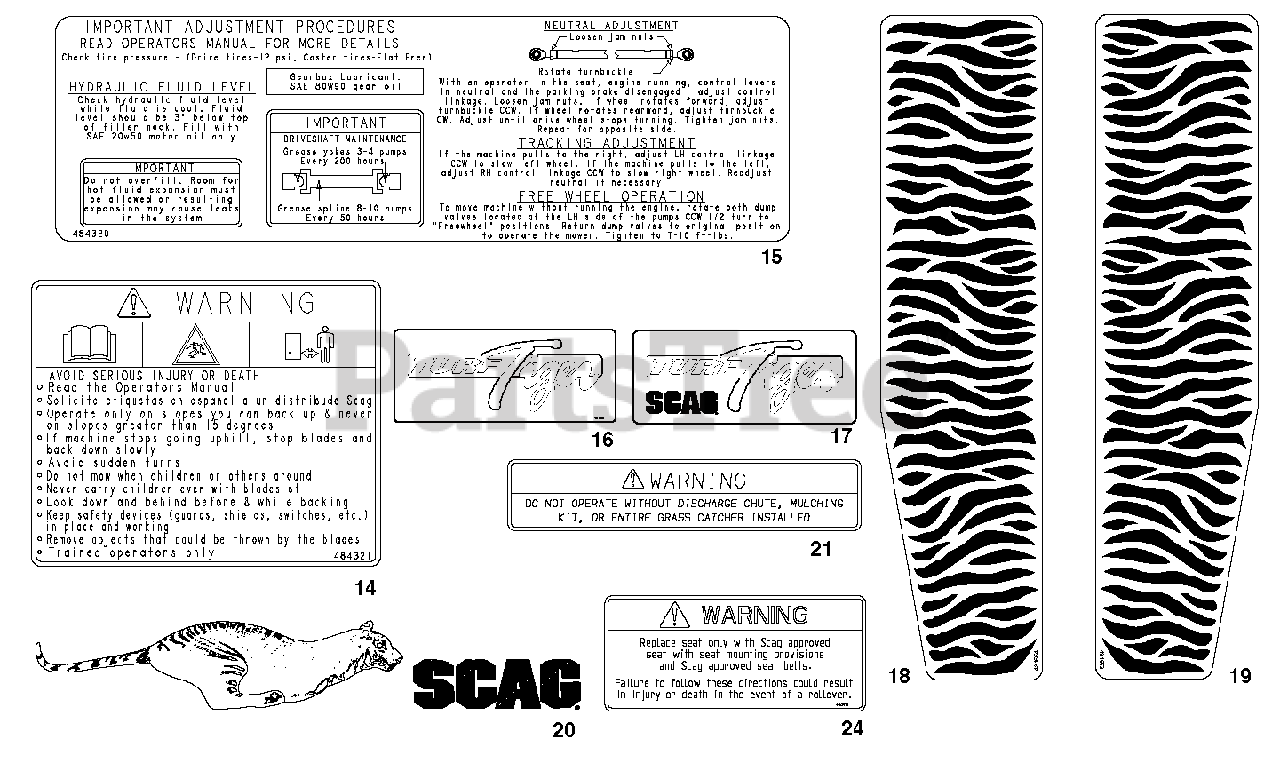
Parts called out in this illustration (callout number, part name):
14	Decal, Fuel Tank Warning
15	Decal, STT Adjustments
16	Decal, Turf Tiger
17	Decal, Turf Tiger
18	Decal, Stripes-RH
19	Decal, Stripes-LH
20	Decal, Tiger
21	Decal, Warning
24	Decal, Seat Replacement
